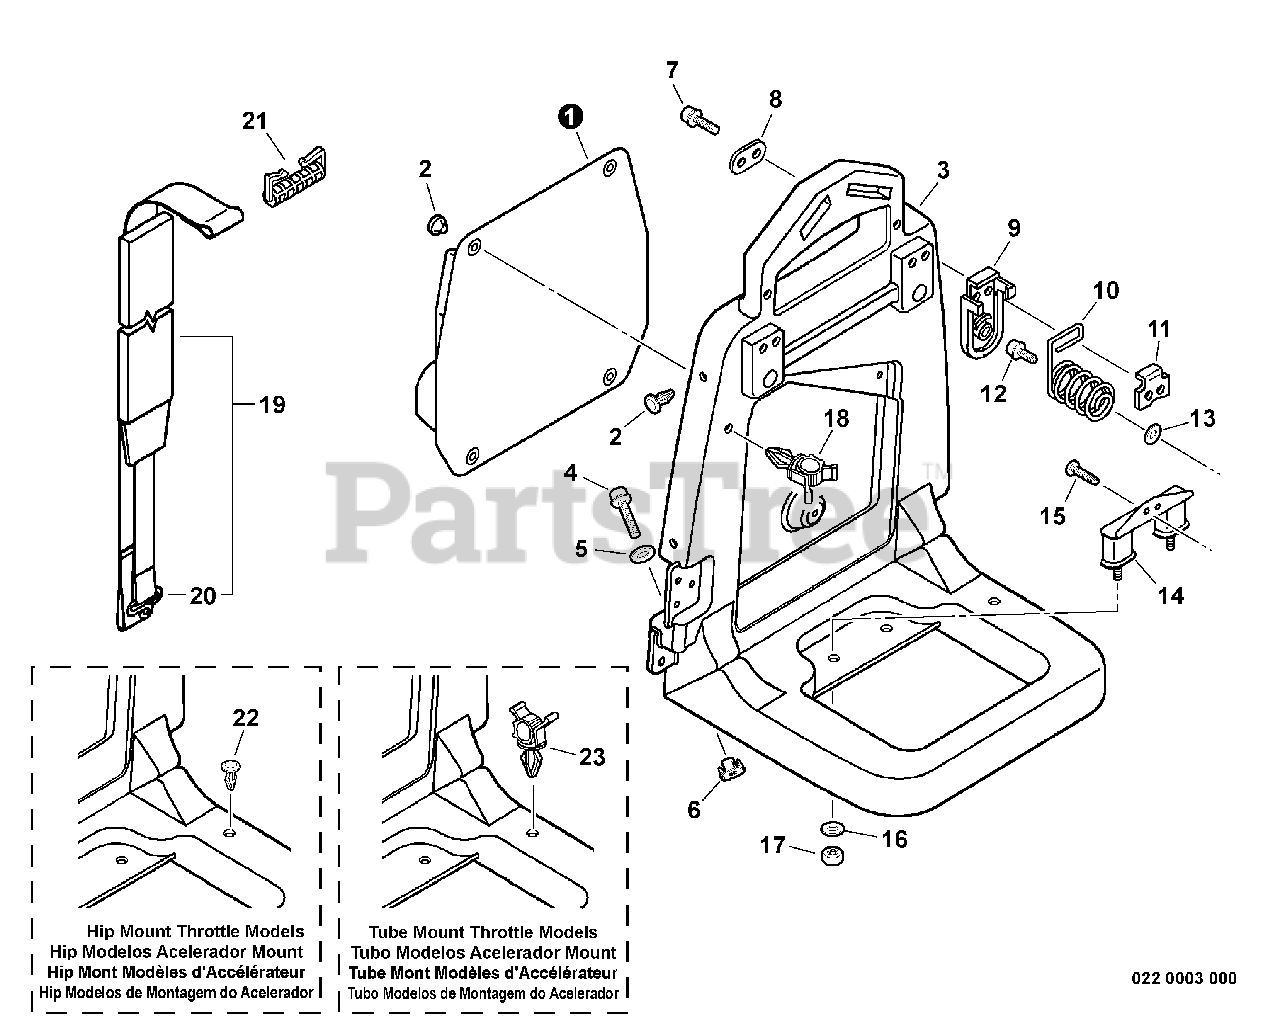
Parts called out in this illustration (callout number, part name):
1	CUSHION, BACKPACK
3	FRAME, BACKPACK
4	BOLT 6×25
5	WASHER 6.6×20×1.6
7	BOLT 5×20
8	PLATE, EYE
9	HOLDER, SPRING
10	SPRING, COMPRESSION
11	PLATE, THREADED
12	BOLT 5×20
13	WASHER 5.5×16×2T
14	CUSHION 5
15	SCREW 5×16
16	WASHER 5.5×18×1
17	NUT, FLANGE M5
18	CLIP, CABLE
19	HARNESS ASSY, BACKPACK
20	RING, HARNESS
21	CLIP, HARNESS
23	CLIP, CABLE
